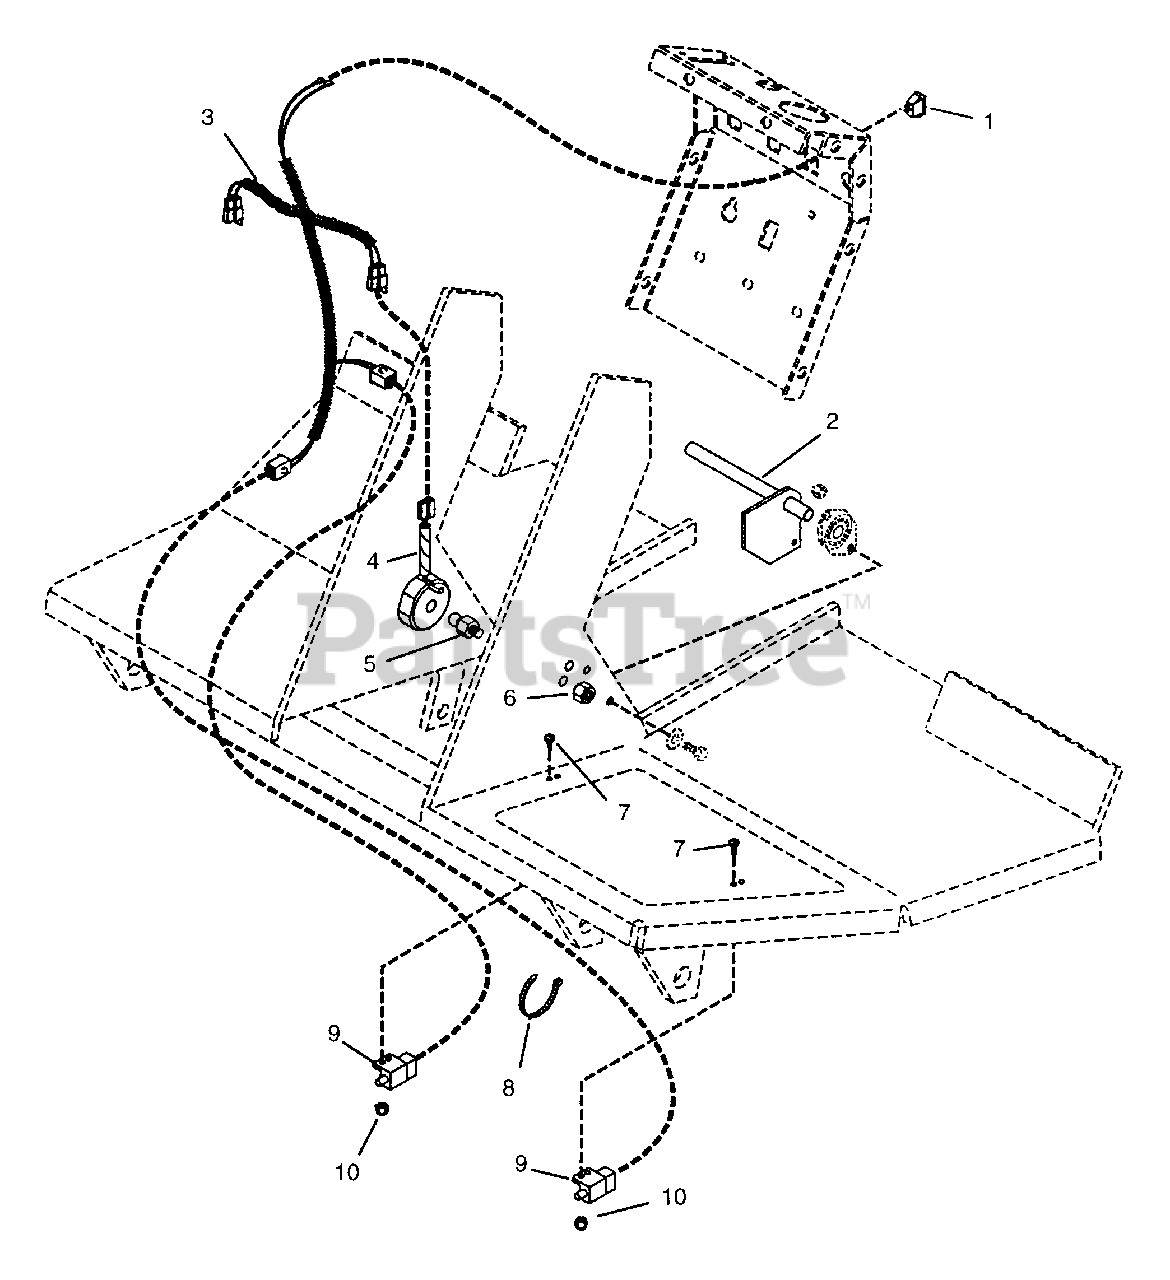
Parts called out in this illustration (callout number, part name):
1	Switch, Light
2	Weldment, Control
3	Harness, Wiring
4	Assembly, Magnet
5	Pin, Magnet
6	Nut-Locking-Nylon .50-13 Grade 5
7	Screw-Machine 10-24 x .625 P/HD
8	Tie Wrap, Black
9	Switch, Interlock
10	Nut-Locking 10-24 Nylon
